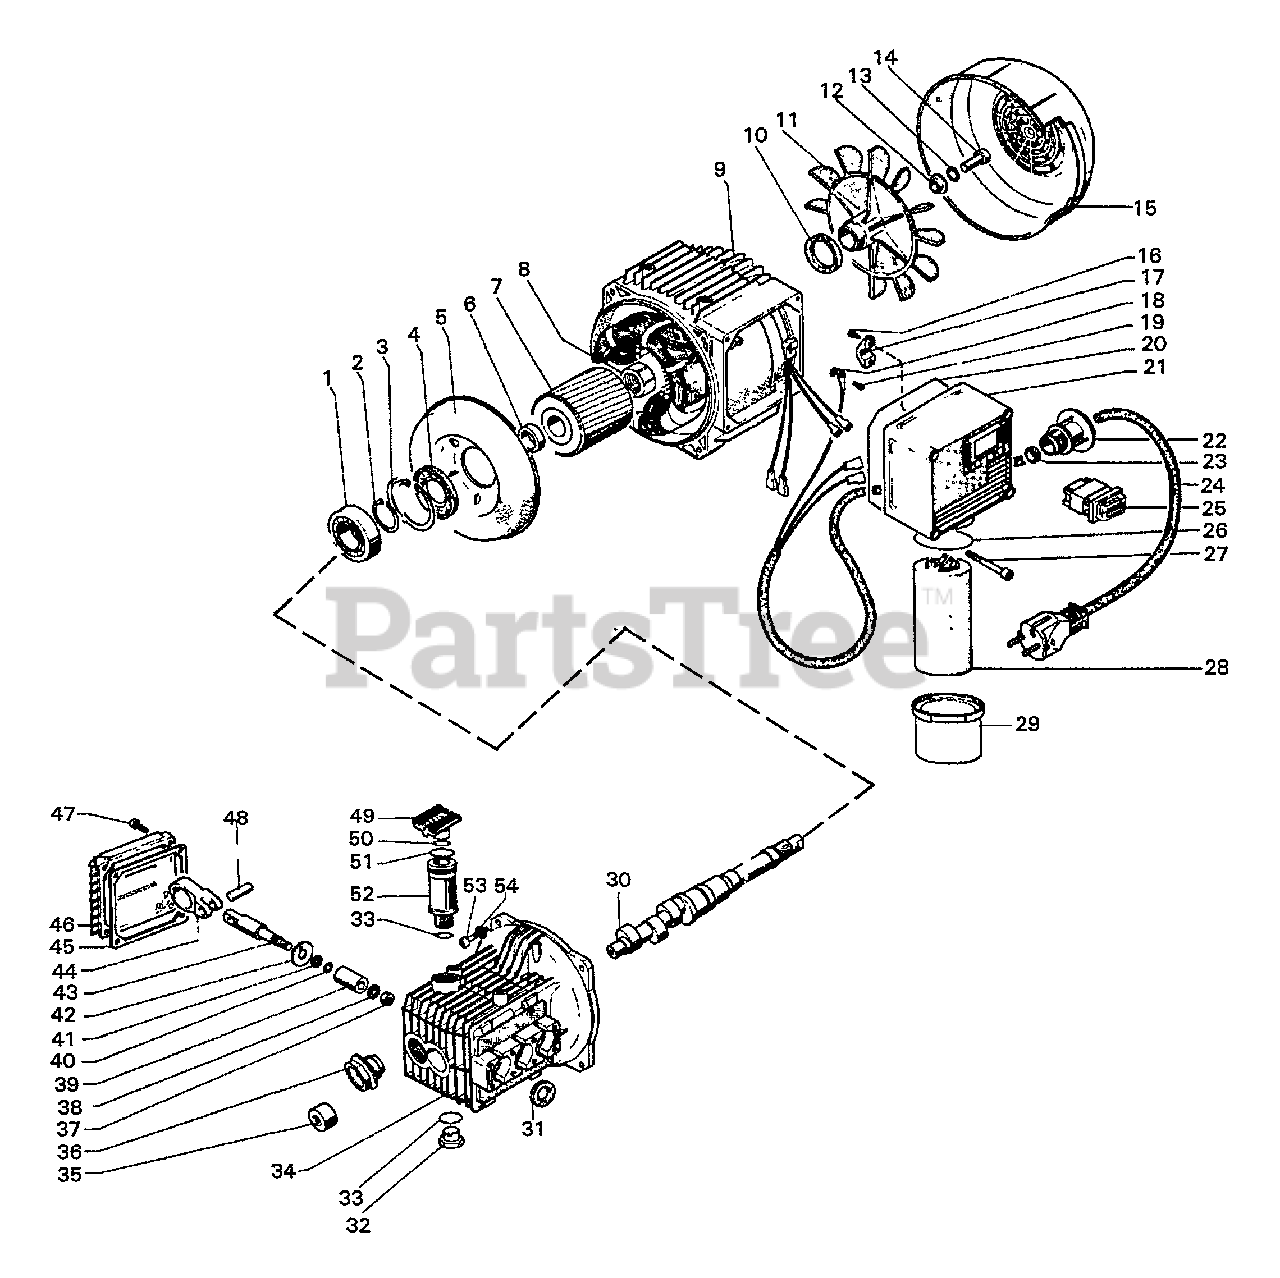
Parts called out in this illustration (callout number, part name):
1	BEARING, BALL
2	RING, RETAINING
3	RING, RETAINING
4	SEAL, OIL
5	COVER, MOTOR
6	SPACER
7	ROTOR
8	NUT - 22
9	STATOR
10	SEAL
11	FAN
12	SPACER, FAN
13	WASHER
14	SCREW - 8X20
15	COVER, FAN
16	SCREW
17	CLAMP
18	WASHER
19	SCREW - 5X12
20	O-RING
21	COVER, SWITCH
22	HOLDER, CABLE
23	GROMMET, CORD GRIP
24	CABLE ASSY
25	SWITCH, IGNITION
26	O-RING, 1.925 X .103
27	SCREW - 5X65
28	CONDENSER
29	COVER, CAPACITOR
30	CRANKSHAFT ASSY
31	OIL SEAL KIT
32	CAP, OIL DRAIN PLUG
33	O-RING
34	CRANKCASE
35	BEARING, NEEDLE
36	INDICATOR - OIL LEVEL
37	NUT - 8
38	WASHER
40	O-RING
41	RING, ANTI-EXTRUSION
42	WASHER
43	GUIDE, PISTON
44	ROD, CONNECTING
45	GASKET, COVER
46	COVER, CRANKCASE
47	SCREW - 6X18
48	PIN, CONNECTING ROD
49	COVER, OIL FILTER
50	O-RING
52	SPACER, DIPSTICK
53	SCREW - 6X25
54	LOCKWASHER - 6
